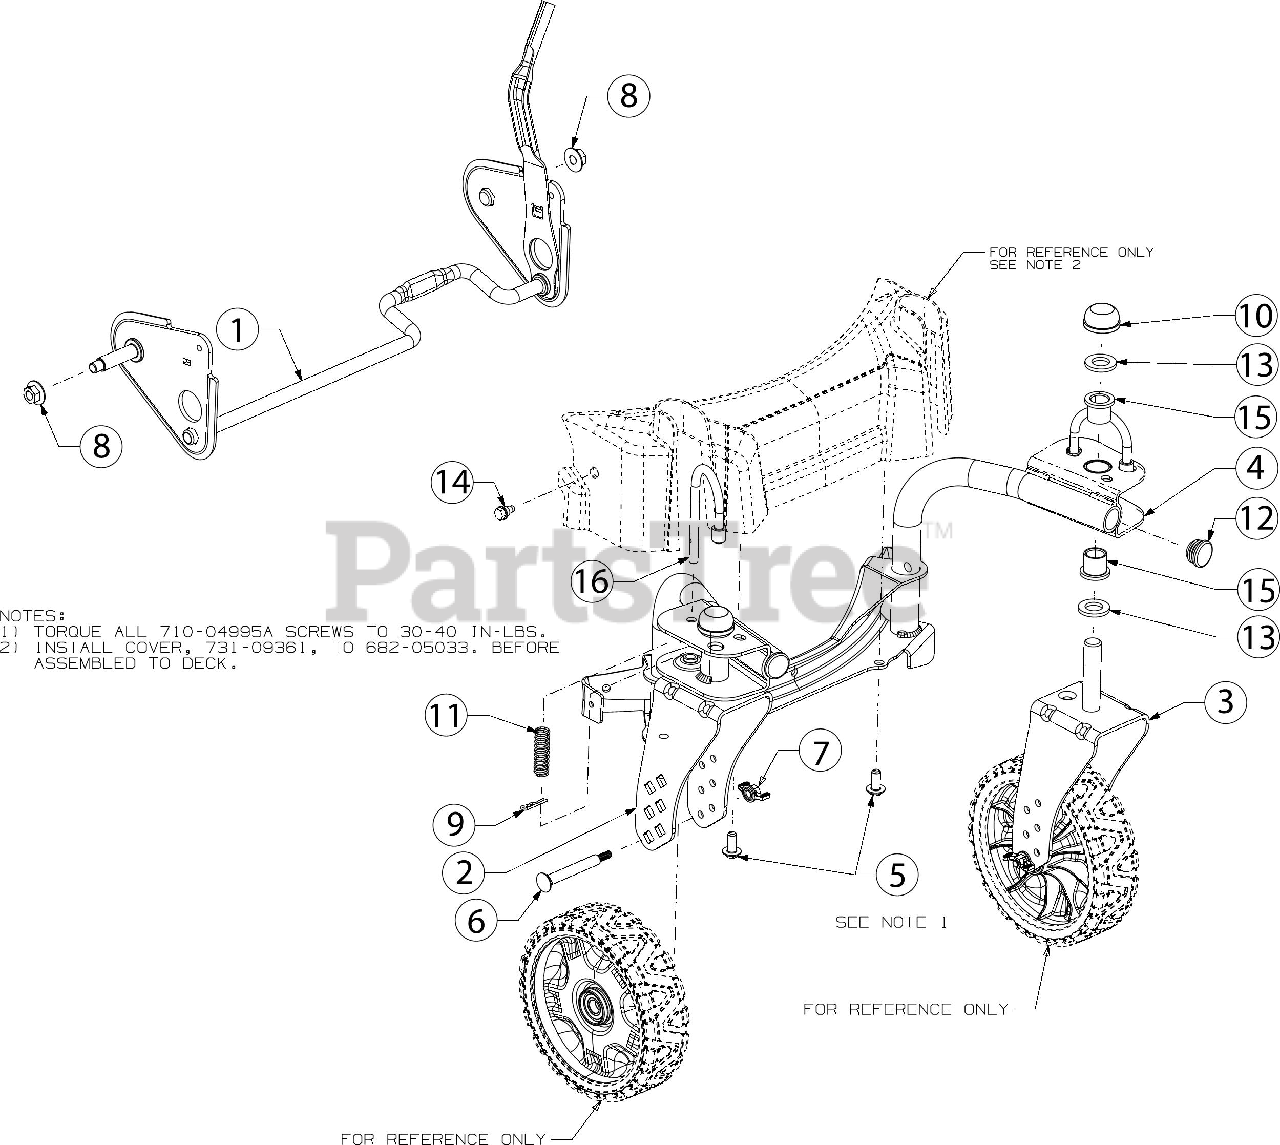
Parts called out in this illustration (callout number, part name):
1	HEIGHT AXLE ASSEMBLY
2	CASTER BRACKET ASSEMBLY (RH)
3	WHEEL BRACKET ASSEMBLY (LH)
4	CASTER BRACKET ASSEMBLY
5	SCREW 5/16-14 x .750
6	CASTER AXLE
7	WING NUT
8	FLANGE LOCK NUT
9	COTTER PIN .072 DIA
10	PUSH CAP
11	COMPRESSION SPRING
12	END PLUG
13	FLAT WASHER
14	SHOULDER SCREW 1/4-20 x .50
15	BEARING:FLANGE .631 ID
16	LOCK PIN
